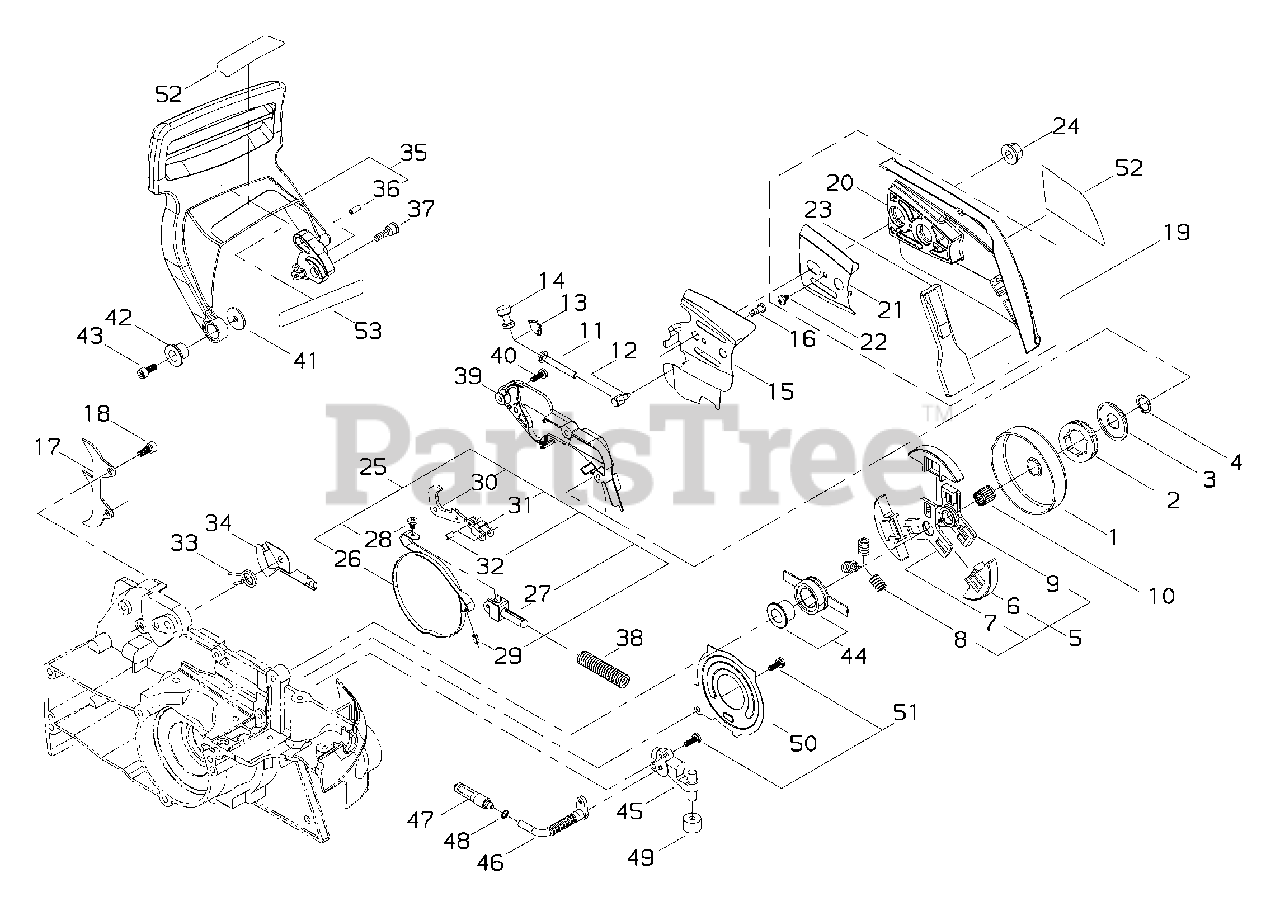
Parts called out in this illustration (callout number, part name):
1	DRUM, CLUTCH
2	SPROCKET, 0.325 RIM
3	COLLAR
4	RING, SNAP Ø10
5	CLUTCH ASSY
6	SHOE SET, CLUTCH (3PCS)
7	BOSS, CLUTCH A
8	SPRING, CLUTCH
9	BOSS, CLUTCH B
10	BEARING, NEEDLE 10
11	SCREW, CHAIN TENSION
12	TENSIONER, CHAIN
13	GUIDE, GEAR
14	SCREW, ADJUSTER
15	PLATE, GUIDE - INNER
16	SCREW M4×7
17	SPIKE, BUMPER
18	BOLT 5×12
19	COVER ASSY, CLUTCH
20	GUARD, SPROCKET
21	PLATE, GUIDE
22	SCREW, TAPPING M4×6
23	PROTECTOR
24	NUT 8
25	BRAKE ASSY, BAND
26	BAND, BRAKE
27	CONNECTOR, BRAKE
28	SCREW, TAPPING M4×10
29	PIN, SPRING Ø4×10 MM
30	LEVER, BRAKE
31	STRAP, TIE
32	PIN, TIE STRAP Ø3×11.8
33	SPRING, TORSION
34	PLATE, RETAINING
35	BRAKE ASSY, CHAIN
36	PIN, LOCATING Ø4×8
37	BOLT
38	SPRING, BRAKE
39	COVER, BRAKE
40	BOLT, ADHESIVE M4×14
41	WASHER 5
42	COLLAR, HAND GUARD
43	BOLT 5×12
44	GEAR ASSY, WORM
45	AUTO-OILER ASSY
46	PIPE, OIL
47	FILTER, OIL
48	CLIP Ø6
49	FILTER, OIL PUMP
50	COVER, OILER
51	BOLT, ADHESIVE M4×14
52	LABEL, MODEL 446S
53	LABEL, CAUTION
